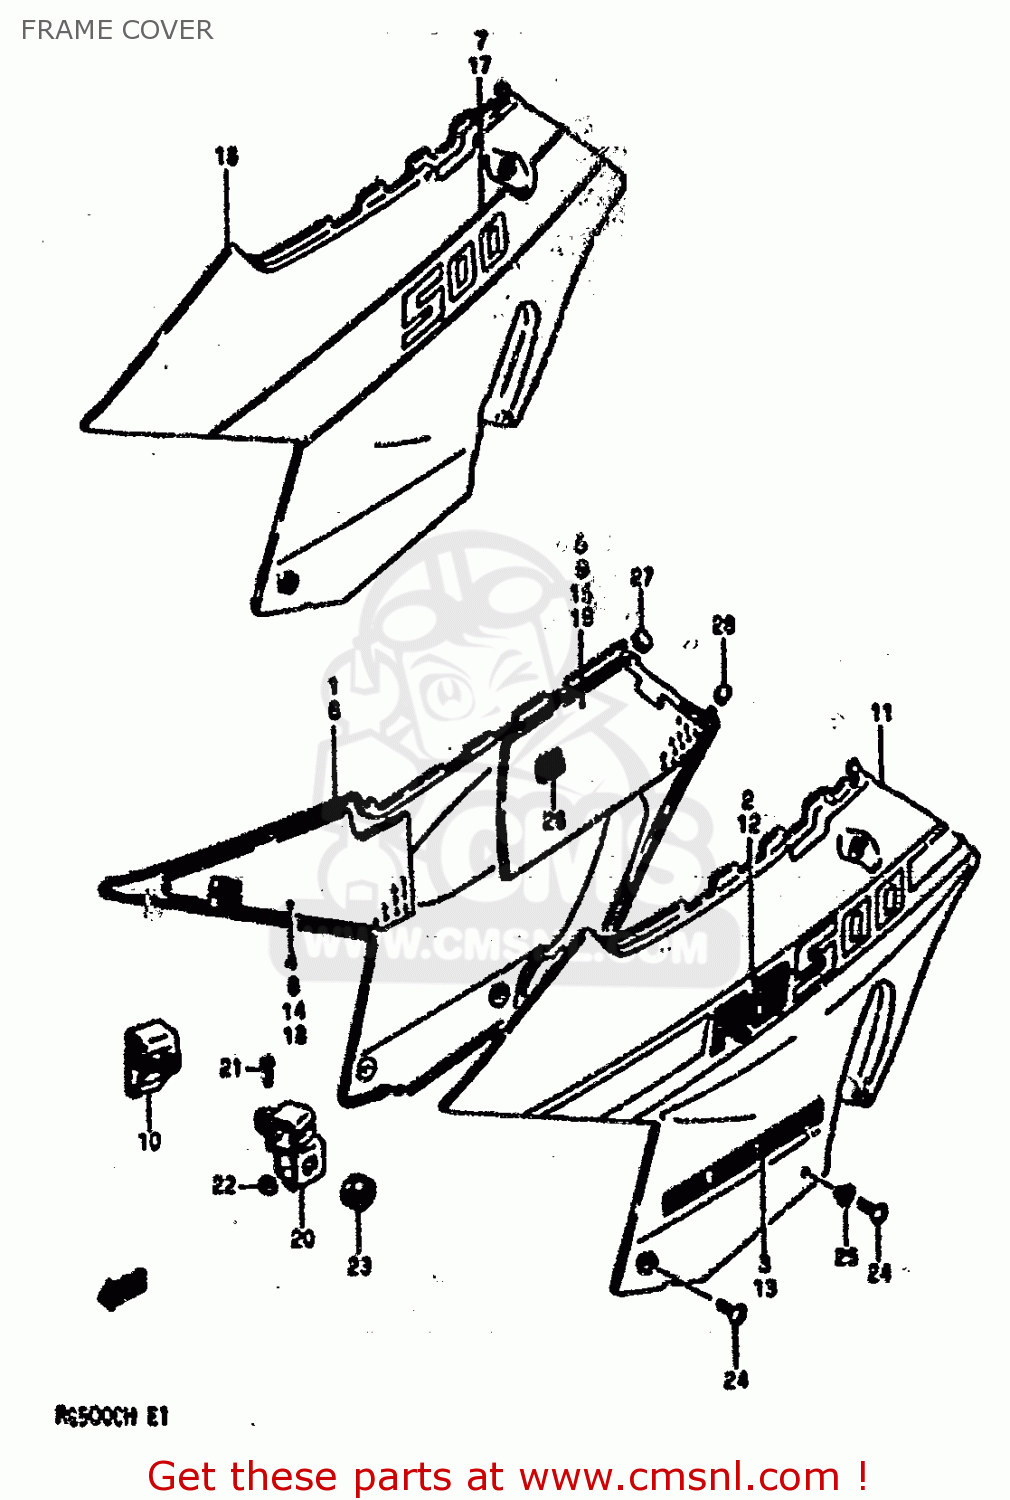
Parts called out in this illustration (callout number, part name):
1	COVER,SIDE R
2	TAPE SET,SIDE
3	EMBLEM
4	SHIELD,SIDE COVER HEAT FR,R
5	HEAT SHIELD,FRONT RH
6	COVER,SIDE RH
7	TAPE SET,SIDE COVER RH
8	SHIELD,SIDE COVER HEAT FR,R
9	HEAT SHIELD,FRONT RH
10	HOLDER,SIDE COVER RH
11	COVER SIDE L
12	TAPE SET,SIDE COVER LH
13	EMBLEM
14	HEAT SHIELD,FRONT LH
15	HEAT SHIELD,REAR LH
16	COVER,SIDE LH
17	TAPE SET,SIDE COVER LH
18	HEAT SHIELD,FRONT LH
19	HEAT SHIELD,REAR LH
20	HOLDER,SIDE COVER LH
21	SCREW
22	NUT
23	CUSHION
24	SCREW(5X10)
25	WASHER(5.2X16X1)
26	CUSHION,SIDE COVER RR
27	CUSHION,SEAT TAIL COVER FR
28	CUSHION,COVER JOINT NO.2
